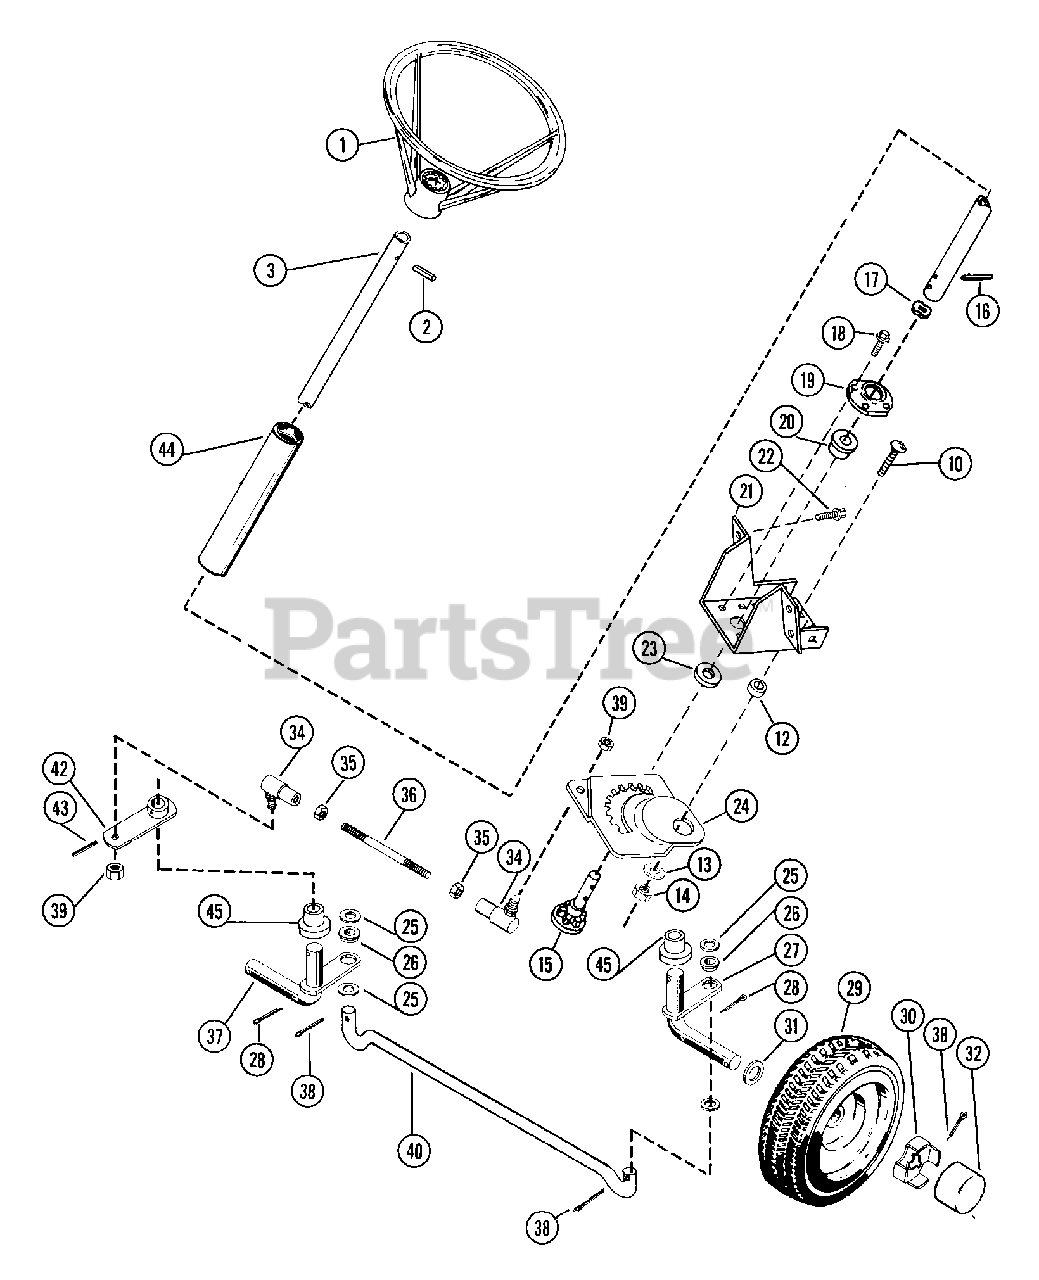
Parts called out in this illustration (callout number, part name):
1	STEERING WHEEL
2	PIN-ROLL .250X1.75
3	STEERING SHAFT
10	BLT-RDHDSQSHNK .38-16X1.00 PL
12	SPACER .380X.750X.236
13	WSHR-FL-STL .390X1.500X.125
14	NUT-LK-JAM-CTR .375-16 PL
15	PINION
16	PIN-ROLL .188X1.00
17	WAVE WASHER .531X.781X.125FH
18	SCR-TAP 10-24X.25 CRSLPH PL 1A
19	RETAINING PLATE
20	BSHG-FLG .625X1.156X.375 SI
21	STEERING BRACKET
22	BLT-SERHFWH .31-18X.50 PL
23	WSHR-FL-STL .630X1.250X.062 PL
24	STEERING GEAR
25	WSHR-FL-STL .505X.875X.024 PL
26	BSHG-FLG.500X.625X.312X.750NY
27	L H WHEEL SPINDLE
28	PIN-COTR .12 X 1.25 PL
29	FRONT WHEEL ASSEMBLY
29	TIRE 4.10/3.50-4
29	WHL
29	ZERK FITTING
29	BSHG-FLG .750X1.380X.750X1.557
30	SPINDLE CUP
31	SPINDLE WASHER
32	HUB CAP
34	BALL JOINT
35	NUT .375-24 PL
36	STEERING LINK
37	SPINDLE
38	PIN-COTR .12X1.0 PL
39	NUT-LK .375-24 PL
40	TIE ROD
43	PIN-GRV .250X1.25 TP A
45	FLANGE BUSHING
